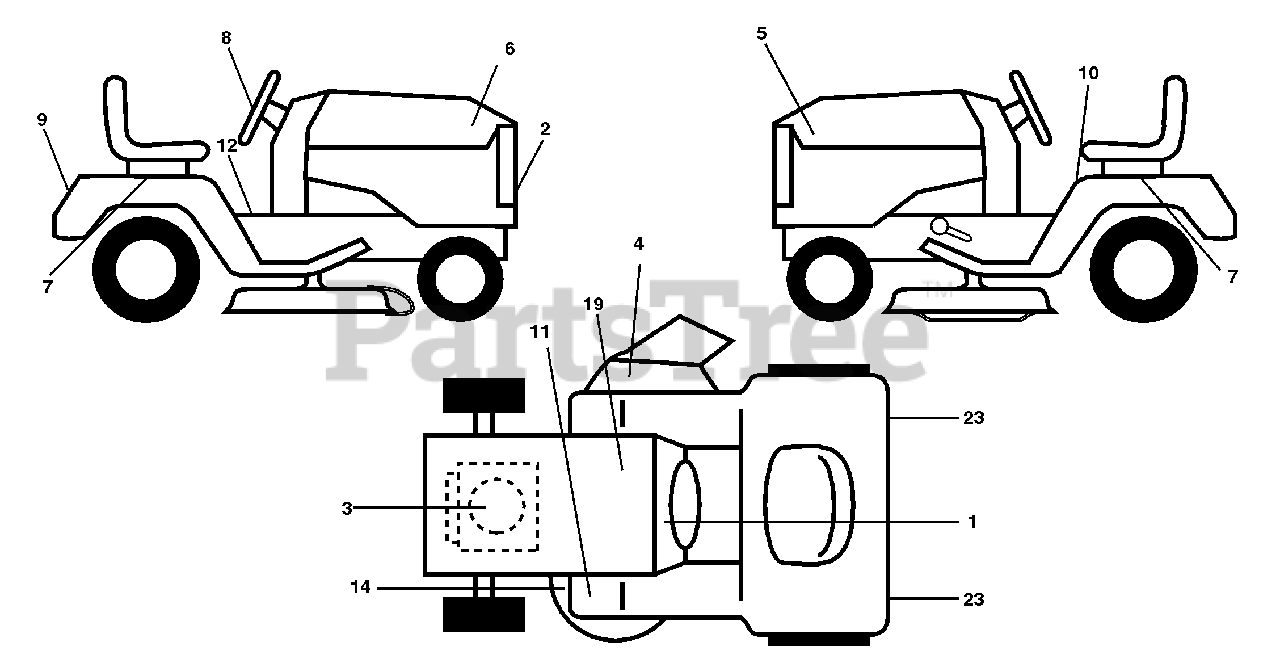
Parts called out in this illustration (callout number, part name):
1	Decal, Operating Instruction
2	Decal, Grille Husqvarna
3	Decal, HP Engine
4	Decal, Warning, Mult. Lang.
5	Decal, Hood LH GTH200
6	Decal, Hood RH GTH200
7	Decal, Fender Automatic Husq.
8	Decal, SW Deluxe Husq.
9	Decal, Fender
10	Decal, Danger
11	Decal, Clutch/Brake
12	Decal, Brake Parking Saddle
14	Decal, V-Belt Schematic
19	Decal, Battery
23	Reflector, Taillight
